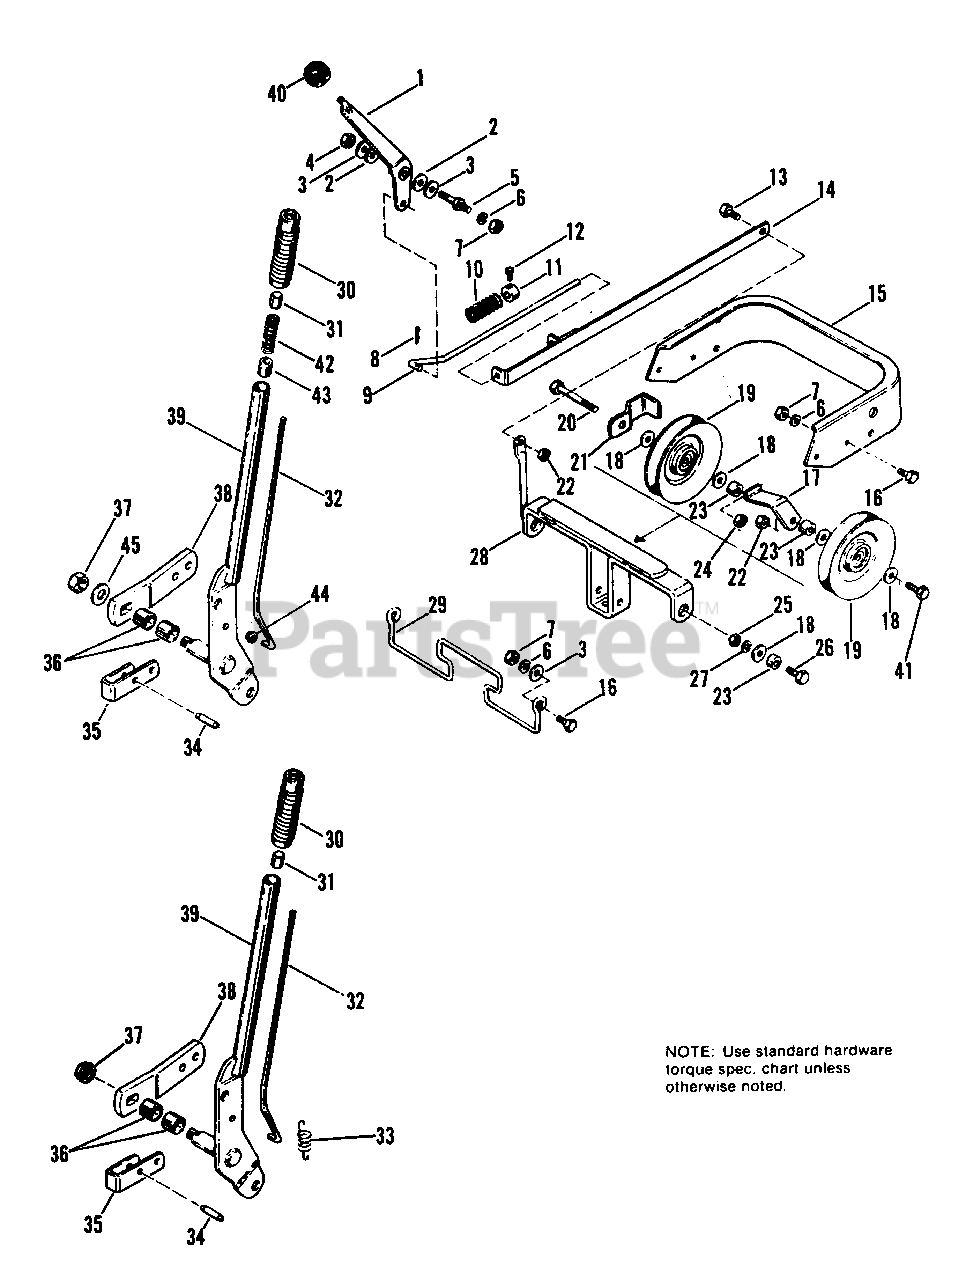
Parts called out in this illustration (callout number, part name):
1	LEVER ASSY.
2	WASHER, Special
3	WASHER, Plain, 5/16
4	LOCKNUT, Hex, 5/16-18
6	LOCKWASHER, 5/16
7	NUT, Hex, Full, 5/16-18
8	PIN, Cotter, 3/32 x 5/8
9	ROD, Clutch, P.T.O.
11	COLLAR, Set
12	SETSCREW, 1/4-20 x 3/8
13	CAPSCREW, Hex Hd., 3/8-16 x 3/4
14	GUIDE ASSY., Idler
15	BUMPER, Front (1690019, 1690020 & 1690106)
15	BUMPER, Front
16	CAPSCREW, Hex Hd., 5/16-18 x 3/4
17	STOP (1690019, 1690020 & 1690106 Only)
18	WASHER, Plain, 3/8
19	PULLEY, Idler
20	CAPSCREW, Hex Hd., 3/8-24 x 1-3/4
21	STOP, Belt (1690019, 1690020 & 1690106 Only)
22	LOCKNUT, Hex, 3/8-16
24	LOCKNUT, Hex, 3/8-24
25	NUT, Hex, Full, 3/8-16 (Qty. 2 on 1690019, 1690020 & 1690106 Only)
26	CAPSCREW, Hex Hd., 3/8-16 x 1
27	LOCKWASHER, 3/8 (Qty. 2 on 1690019, 1690020, & 1690106 Only)
28	CLEVIS ASSY., Pulley
29	STOP, Belt, P.T.O.
30	GRIP, Lift Lever (1690019, 1690020 & 1690106 0nly)
30	GRIP, Lift Lever
31	BUTTON, Thumb (1690019, 1690020 & 1690106)
31	BUTTON, Thumb
32	ROD, Latch (1690019, 1690020 & 1690106 Only)
32	LEVER, Lift
33	SPRING (1690019, 1690020 & 1690106 Only)
34	PIN, Roll, 3/8 x 1
35	LATCH, Lift Lever
37	LOCKNUT, Flange, 1/2-13
38	LINK, Lift Lever
39	LEVER ASSY., Lift (1690019, 1690020 & 1690106)
39	LEVER ASSY., Lift
41	CASPCREW, Hex Hd., 3/8-24 x 2 (1690019, 1690020 & 1690106 Only)
42	SPRING (990904 Only)
43	SPACER (990904 Only)
44	PUSHNUT (990904 Only)
45	WASHER, Plain (990904 Only)
